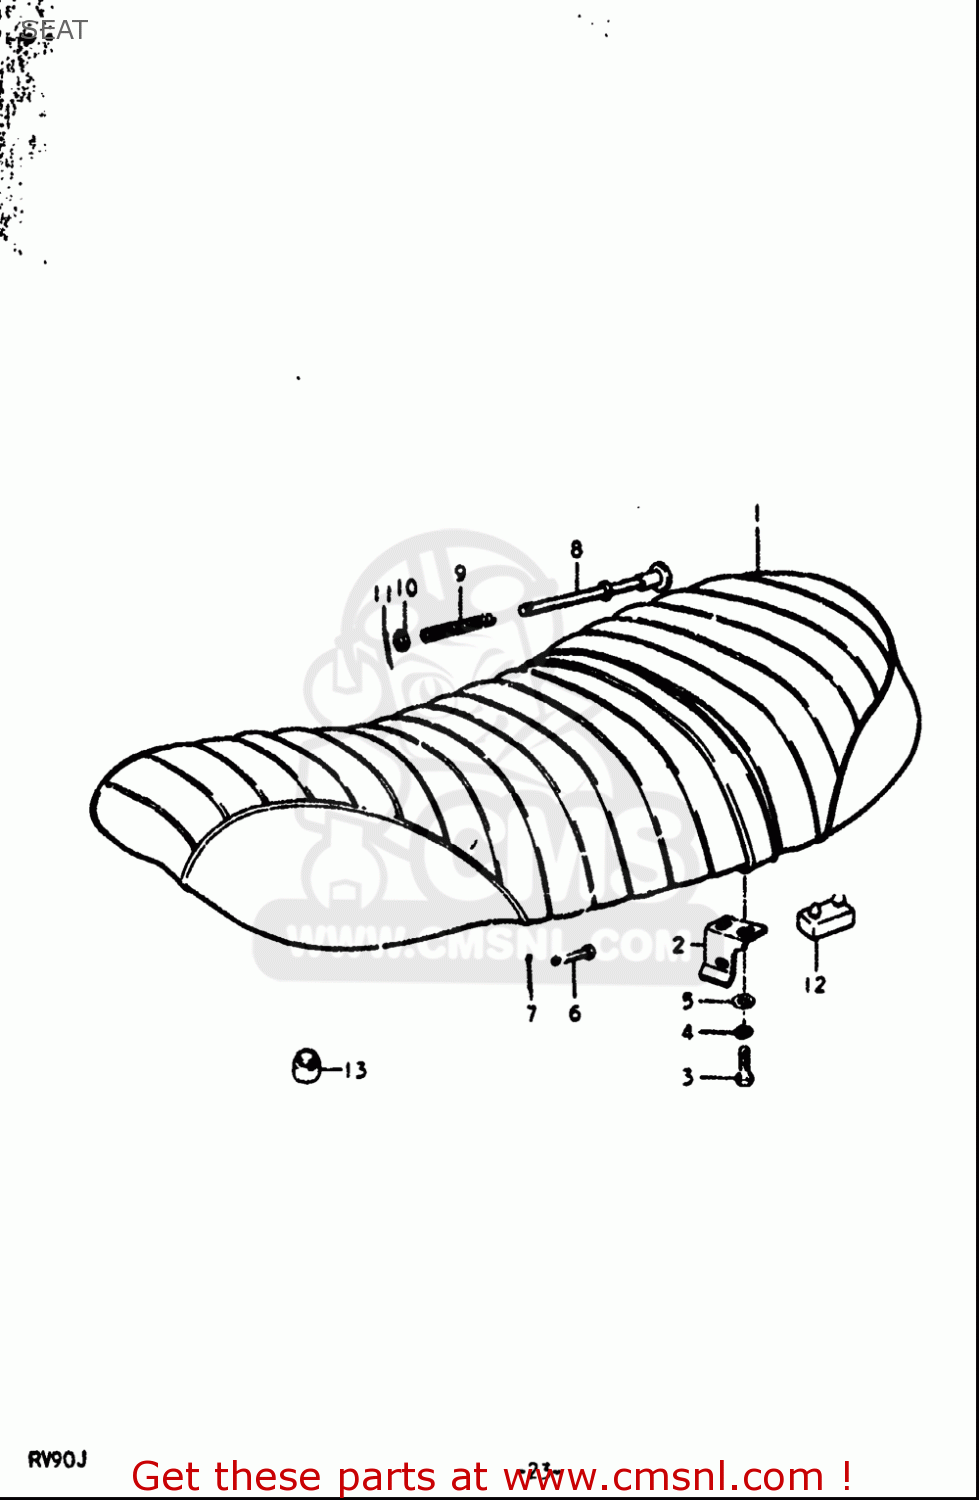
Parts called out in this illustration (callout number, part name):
1	SEAT ASSY(BLACK)
3	BOLT(6X14)
4	WASHER,LOCK
5	WASHER
6	PIN
7	PIN
8	BAR,SEAT CLAMP
9	SPRING
10	WASHER
11	PIN
12	CUSHION
13	CUSHION
